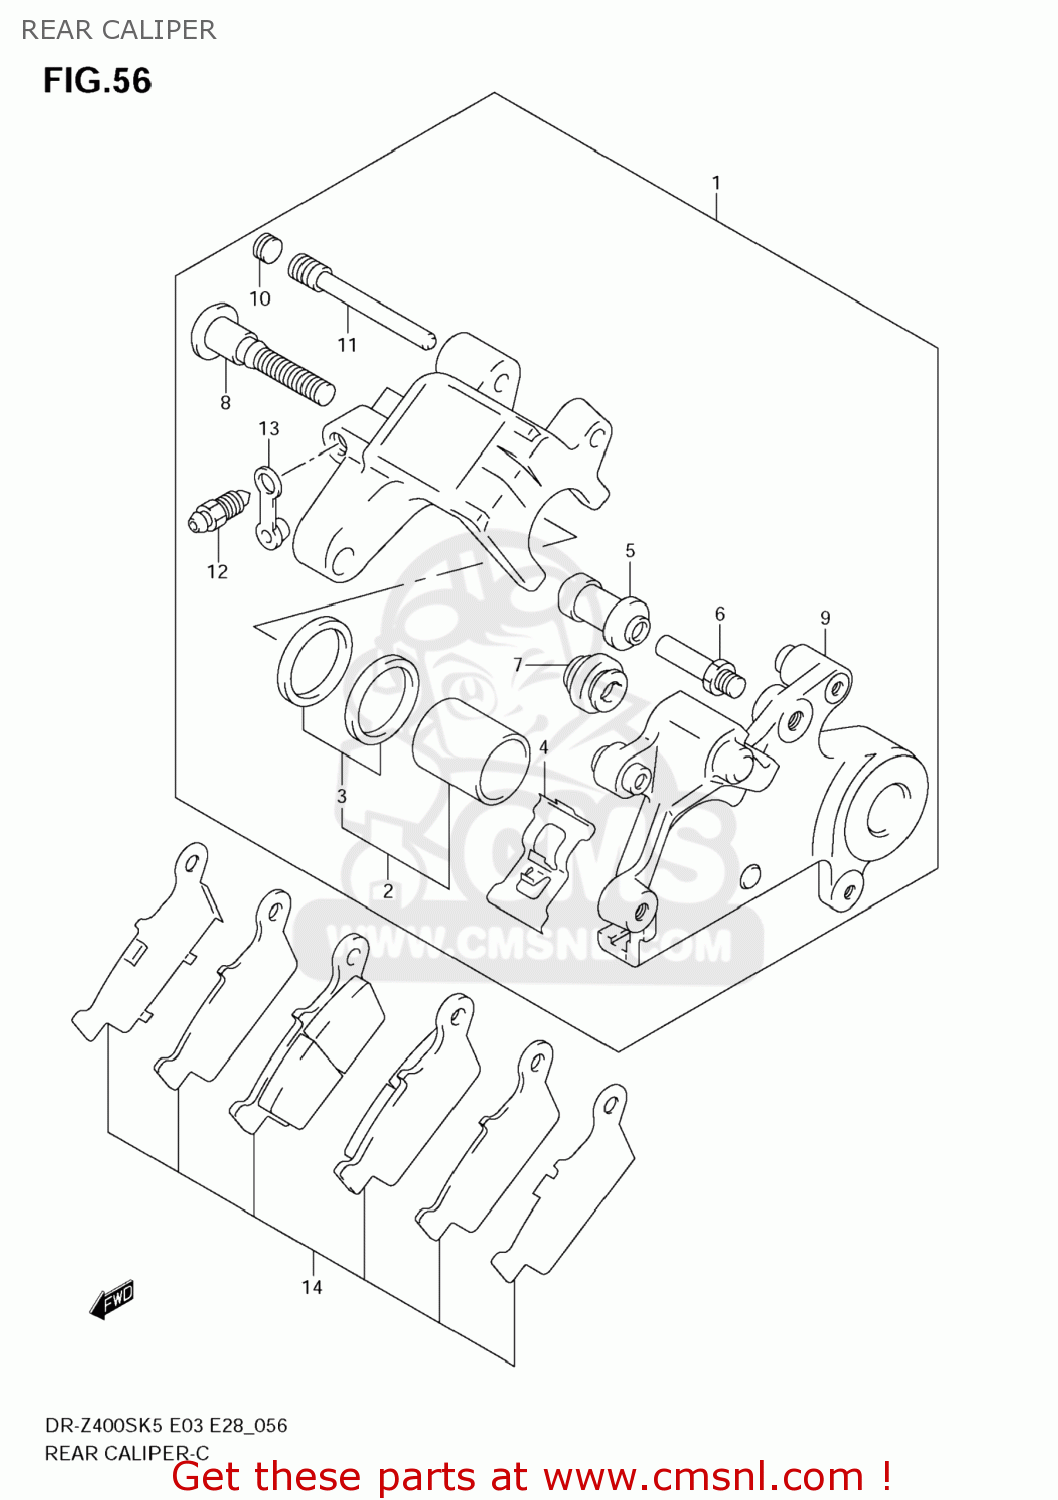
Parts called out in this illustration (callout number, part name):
1	CALIPER ASSY,RR
2	PISTON SET
3	SEAL SET,PISTON
4	SPRING,PAD
5	BOOT
6	BOLT
7	BOOT
8	PIN,BOLT
9	BRACKET
10	PLUG,PIN
11	PIN,HANGER
12	BLEEDER
13	CAP,BLEEDER
14	PAD & RETAINER SET
